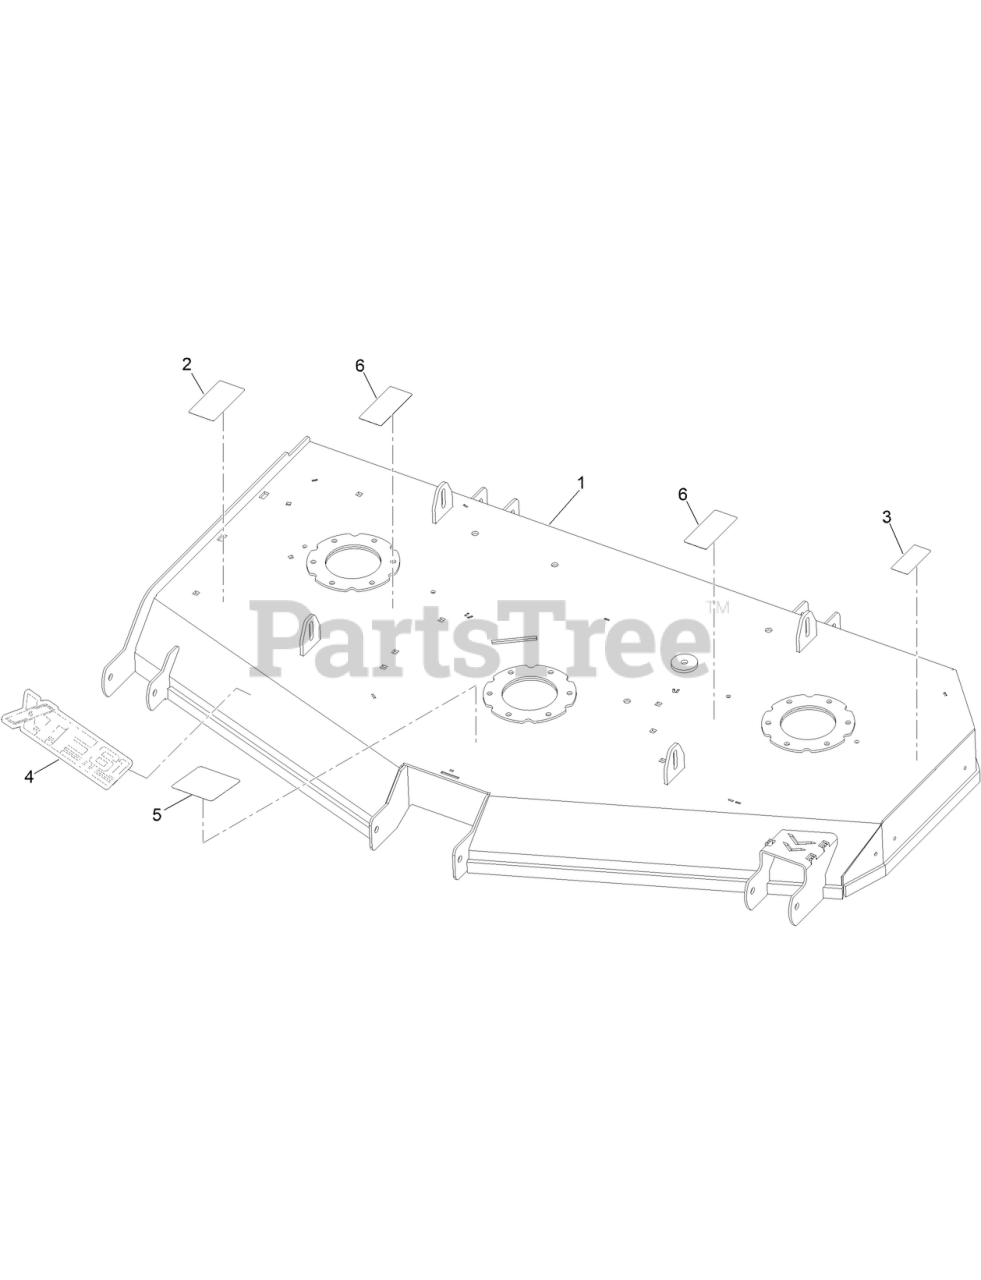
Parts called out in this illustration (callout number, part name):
2	DECAL-DANGER, DECK
3	DECAL-SAFETY BLADE TORQUE
4	2020 XTF-61 DECAL
5	DECAL-DECK BELT ROUTING
6	DECAL-ROTATING FAN HAZARD
